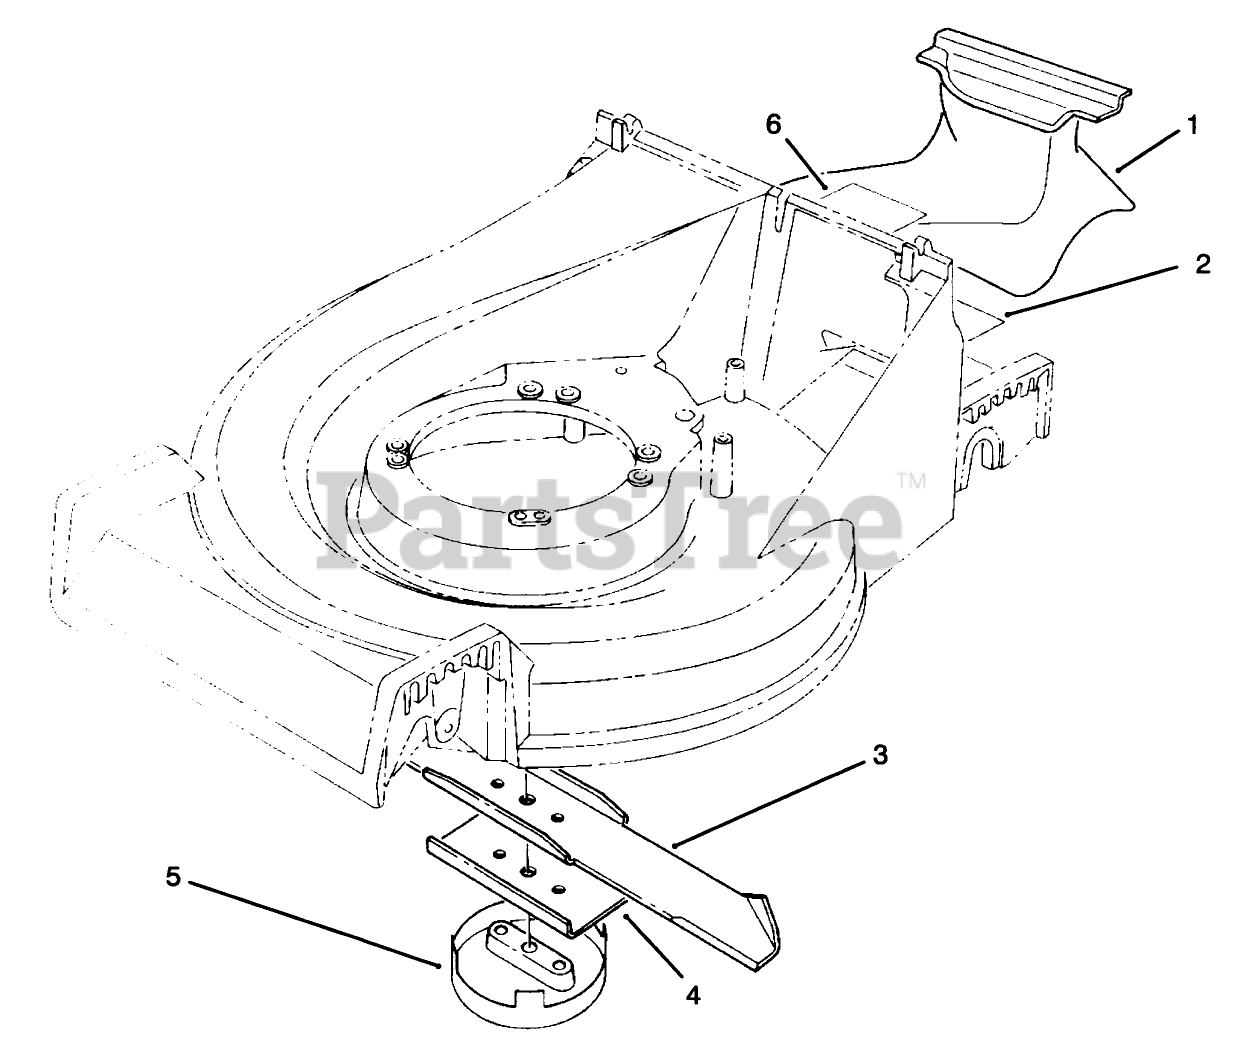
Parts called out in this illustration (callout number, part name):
1	RECYCLER PLUG
2	DECAL - MULCHER KIT
3	BLADE-21in
4	Stiffener
5	CUP-SCALP, ANTI
6	DECAL - FRENCH
